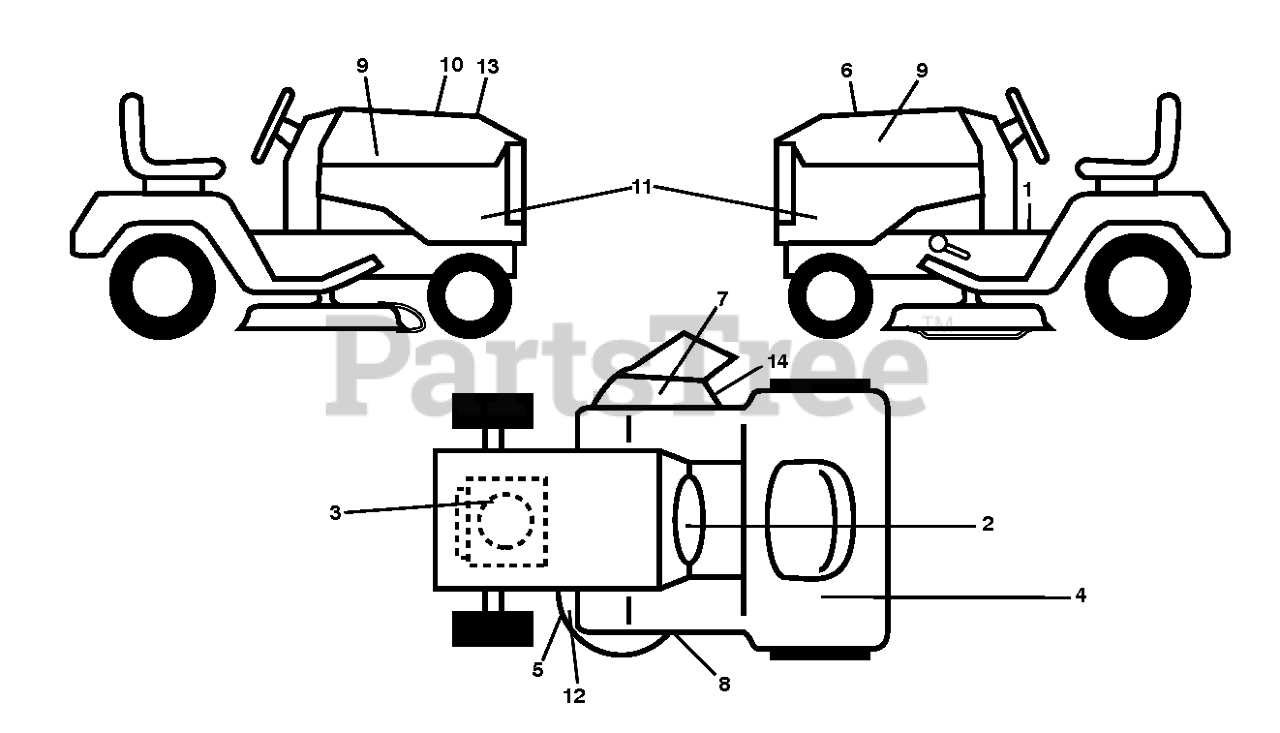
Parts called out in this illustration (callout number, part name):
1	DECAL.FENDER.WARNING.ENGLISH
1	DECAL.FENDER.WARNING.ENG
1	DECAL.WARNING.2007.ENG/FR
1	DECAL TRACTOR LOWES DECAL DECA
2	DECAL, WARNING SPARK ARRESTOR
2	DECALS.WARN.CA.SPKARREST/PROP
2	DECAL BTRY SYMBOLS
3	DECAL.ENG.BS.24INTK.DOM.381710
3	DECAL.ENG.BS.INTK.24HP.382016
3	DECAL.ENGINE.B&S
3	Decal, Eng. HP
4	DECAL.DECK.BUILTINAMERICA.HUSQ
4	DECALS
5	DECAL.MOWER.SCH.48/54.PREM
5	DECAL.MOWER.CAUTION.TENSION.AR
5	DECAL
6	DECAL.RPL.BSM44.INTK.TLW
6	Decal, Replacement
6	DECAL.RPL
7	DECAL, DECK DEFLECTOR, WARNING
7	DECAL.DECK.DEFLECTOR.WARNING
8	DECAL.DECK.BELT.ROUTING.48/54
8	DECAL.MOWER.SCH.48/54.PREM
9	DECAL.BADGE.170MM.TEXTLOGO.
9	DECAL.WB.178MM.15.HUSQ.NEWBRAN
10	DECAL.WARNING.CUST.RESP.E85.
11	DECAL PANEL SD
11	DECAL SDPNL.YTH24V54.B&S.HUSQ
12	DECAL.WARN.KEEP.HAND.AWAY
12	DECAL.DECK.STAMP.BIOCLIPCMP.HU
12	DECAL.MOWER.SCH.48/54.PREM
12	DECAL.MOWER.CAUTION.TENSION.AR
13	DECAL.RPL.BSM44.INTK.TLW.54
13	DECAL.RPL.BSM44.INTK.TLW.54.K4
13	DECAL.ETHANOL.E85 WARNING SYMB
13	DECAL.E85.WARNING.2012
14	DECAL.MOWER.SCH.48/54.PREM
